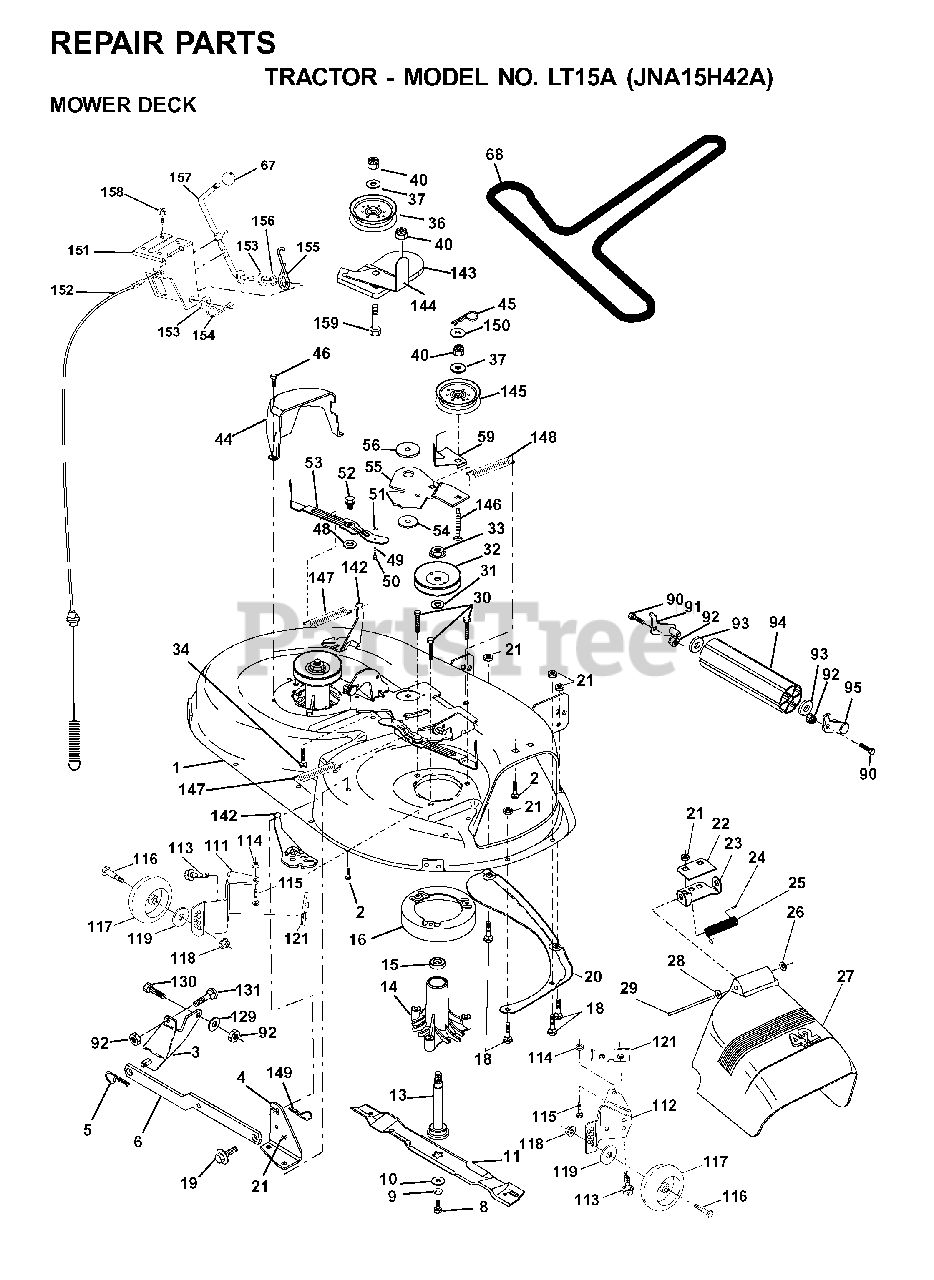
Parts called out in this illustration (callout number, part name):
1	42" DECK KIT
2	BOLT
3	BRKT ASM SWAY BAR
4	BRACKET SWAY BAR 42" DECK
5	RETAINER-SPRNG RB
6	REAR SUSP ARM
8	BLADE BOLT
9	LOCKWASHER
10	WASHER.BLADE
11	BLADE 42"
13	SHAFT ASM VENT
14	HSG MANDREL
16	STRIPPER, MWR ROUND
18	BOLT
19	BOLT SHD 5/16-18
20	BAFFLE.VORTEX
21	LOCKNUT
22	STIFFENER BRACKET
23	DEFLECTOR BRACKET
24	CAP-SLEEVE LT
25	SPRING TORSION
26	NUT PUSH M
27	SHIELD DEFLECTOR
28	WASHER
29	ROD.HINGE
30	SCREW THDROL ROLLING WASHER HD
31	WASHER
32	PULLEY/MANDREL
33	NUT
34	BOLT
36	FLAT IDLER PULLEY
40	LOCKNUT
44	GUARD MANDREL LH BLACK
45	RETAINER M
46	SCREW.1/4-20X5/8
49	ROLLER ASM CAM FOLLOWER
50	BOLT
53	ARM
54	HARDENED WASHER
55	ARM IDLER 42" MOWER LT/YT
56	SPACER.RETAINER.MOWER
59	GUARD, BELT
67	KNOB T (3/8 HOLE)
68	BELT V SECONDARY
90	SCREW
91	BRACKET ASM, ROLLER (L)
92	NUT
94	NOSE ROLLER
95	BRACKET ASM, ROLLER (R)
111	BRACKET WHEEL GAUGE LH 42" DK
112	BRACKET WHEEL GAUGE RH 42" DK
114	NUT
115	BOLT
116	PEDAL COVER T
117	WHEEL.GAUGE.STANDARD
118	LOCKNUT
119	WASHER
121	BRACKET.EXTRD.GWL
129	WASHER
131	BOLT D
142	ARM SPRING BRAKE MOWER
144	KEEPER.BELT.42".CLUTCH.CABLE
145	PULLEY
146	BOLT, CARRIAGE IDLER BLACK
147	SPRING EXTENSION
148	IDLER RETURN SPRING
149	SPRING.RETAINER.YELLOW.ZINC
150	WASHER PM
151	BRACKET, CLUTCH CABLE
152	CLUTCH CABLE 42"
153	WASHER FLAT 3/8"
154	SPRING RETAINER
155	SPRING RETENTION LEVER
156	SPACER CLUTCH CABLE
157	ROD CLUTCH CABLE 3/8"
158	SCREW LT
159	BOLT
532134149	BLADE.42".MULCH
